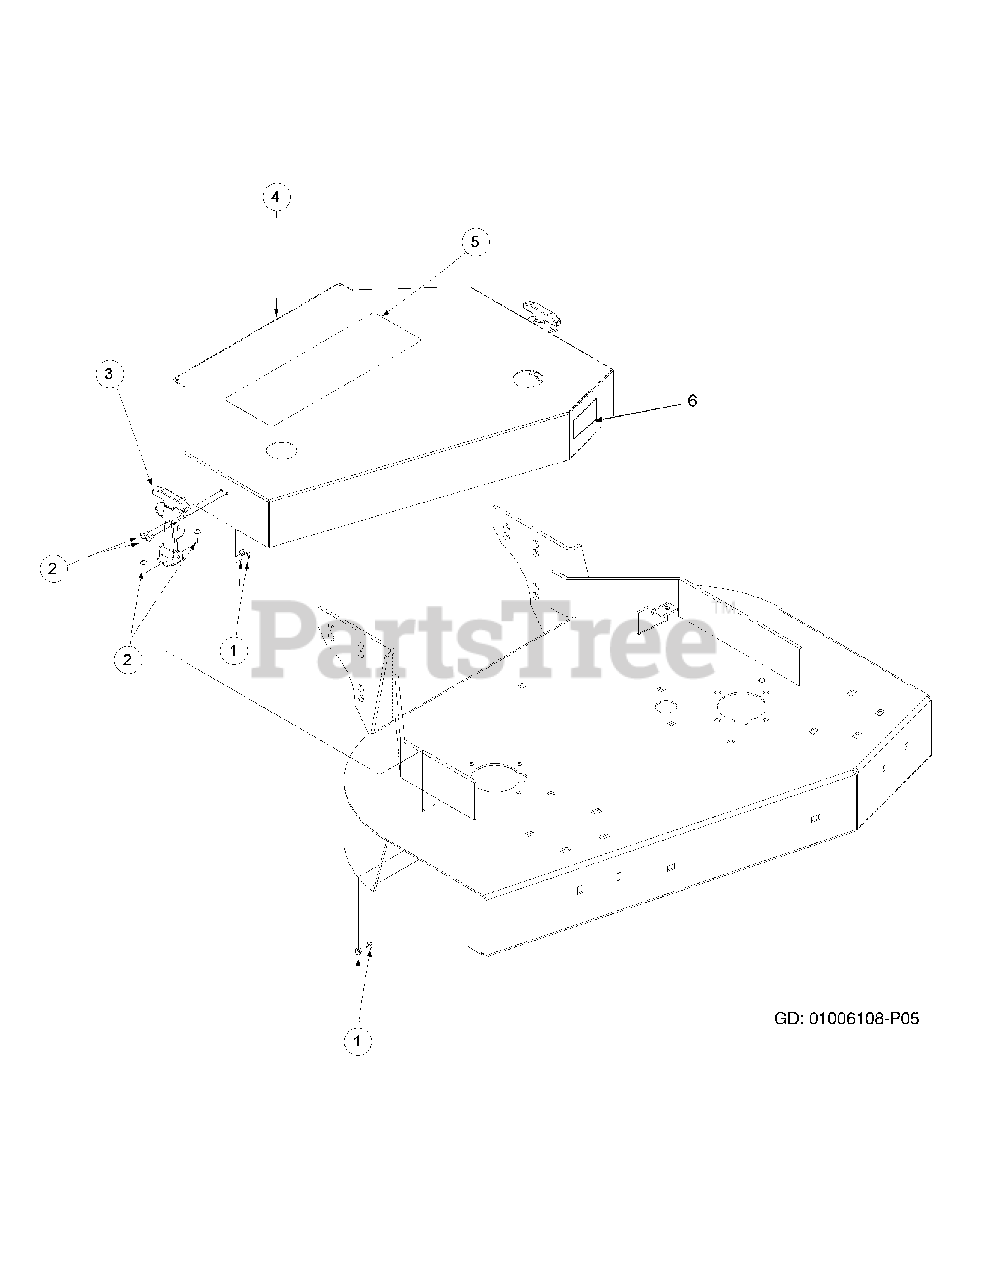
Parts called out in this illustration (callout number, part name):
1	Lock Nut, Nylon Insert
2	Machine Screw, 10-24 x 1/2
3	Rubber Hood Latch
4	Deck Cover, 36
5	Label Commercial Mower
